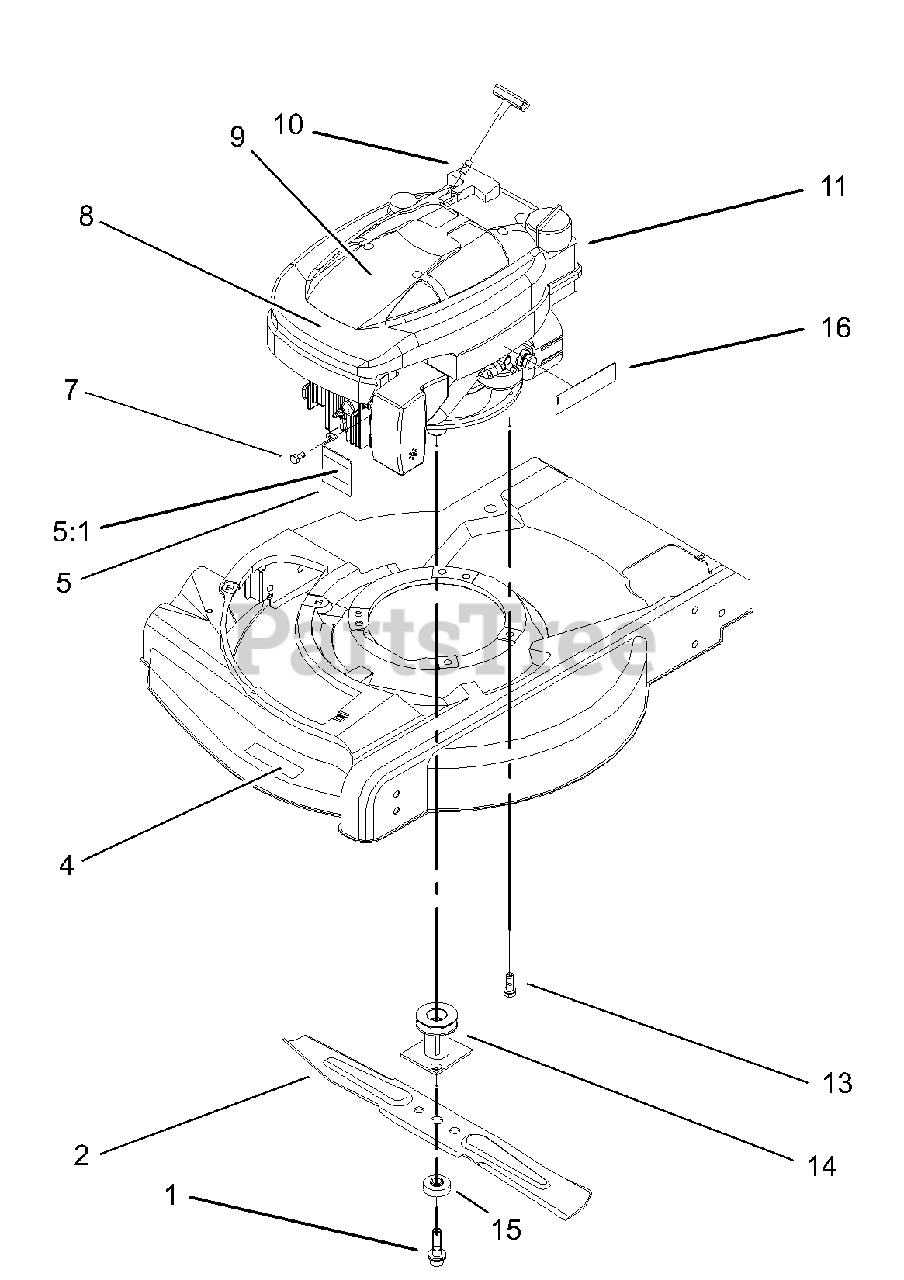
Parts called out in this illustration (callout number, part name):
1	Bolt-Blade,Sems
4	Decal-Deck
5	ASM-Guard,Muffler
5:1	Decal-Surface, Hot-International
7	Screw-HWH
8	Applique
9	Decal-Recoil, Lb
10	Stop-Rope
13	Screw-Taptite W/Patch
14	Driver-Blade, ASM
16	Decal-Primer
